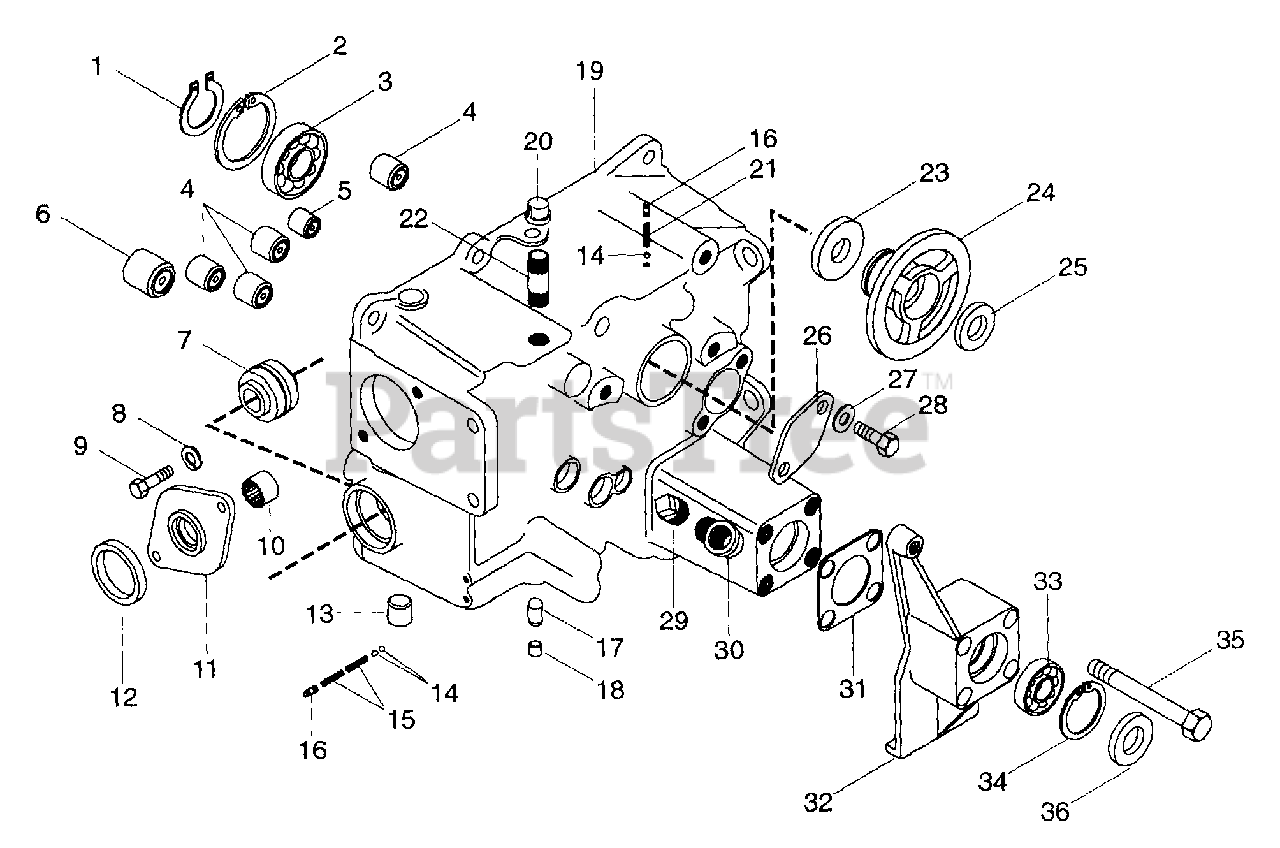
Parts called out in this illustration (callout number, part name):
1	Ring-Retaining-External 1.819 x .062
2	Ring-Retaining-Internal 3.52 x .109
3	Bearing-Ball 1.97 x 3.14 x .63
4	Bearing-Needle .75 x 1.0 x .75
5	Bearing-Needle .625 x .812 x .75
6	Bearing-Needle 1.0 x 1.25 x .75
7	Bearing-Assembly 1.000 x 1.980 x 1.243
8	Washer-Lock .313 x .078
9	Bolt-Hex .31-18 x 1.00 Grade 5
10	Bearing-Needle .75 x 1.000 x .50
11	Cap, Front PTO
12	Seal .750 x 1.250 x .136
13	Plug, Cup .500
14	Ball, .312
15	Spring-Compression .045 x .30 x 1.50
16	Plug, Pipe .12
17	Pin, Interlock
18	Plug, Cup; 3/8
19	Assembly, Transmission Case
20	Cap, Pipe 1/2
21	Spring-Compression .045 x .300 x .938
22	Nipple, Pipe .50 x 2.50
23	Seal 2.250 x 3.002 x .375
24	Hub, Clutch
25	Seal .750 x 1.628 x .250
26	Plate, Cover
27	Washer-Flat-Steel .406 x .812 x .065
28	Bolt-Hex .38-16 x .75 Grade 5
29	Plug, Pipe .50
30	Elbow .50 x 90
31	Gasket
32	Retainer, Axle Bearing
33	Bearing-Ball 1.25 x 2.25 x .50
34	Ring-Retaining-External 2.49 x .078
35	Bolt-Hex .50-13 x 3.25 Grade 5
36	Seal 1.250 x 2.250 x .500
